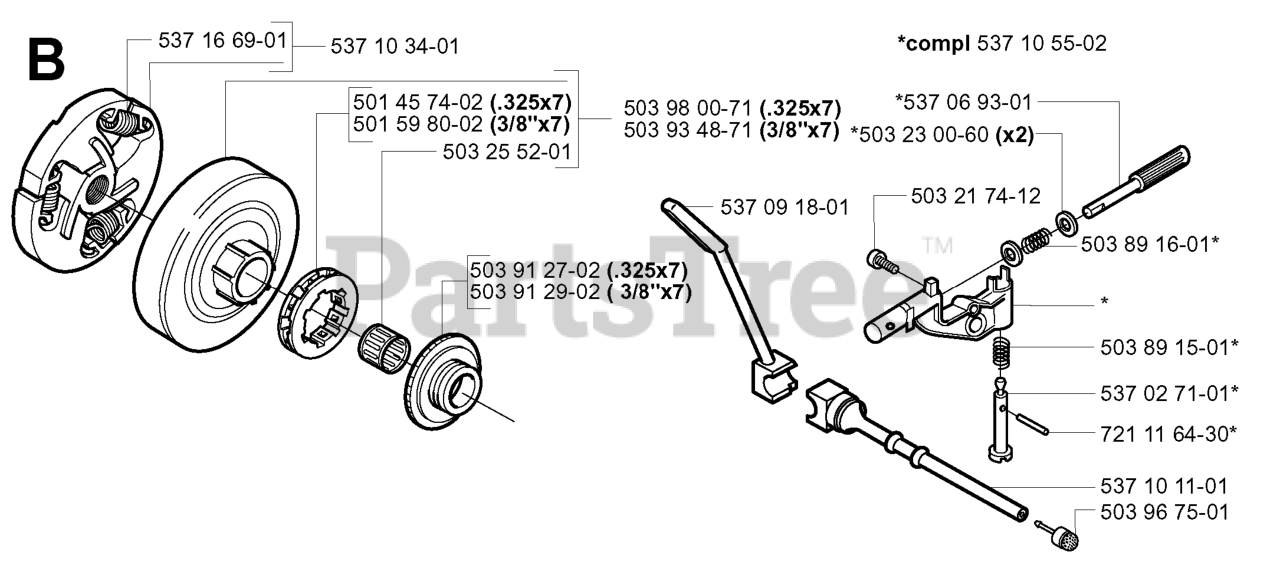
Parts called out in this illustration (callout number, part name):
1	RP SEAT
2	SEAT PIVOT BRKT
3	BOLT, HEX 3/8-16X1
6	NUT
7	SPRING COMPRESSION
8	SCREW 3/8-16X1
9	WASHER
10	PAN.ASM.SEAT.1SLOT
11	KNOB.SEAT.ADJ.WINGNUT
12	BRKT.MNTNG.SWITCH.SEAT.BLACK
14	BOLT.ROUND.HEAD.SQUARE.NECK
15	SPACER SPLIT 28X.96
17	NUT T
21	BOLT.SHOULDER.5/16-18
22	NUT.71038.31-18.HEX.NYLOCK
25	BOLT,SHOULD
